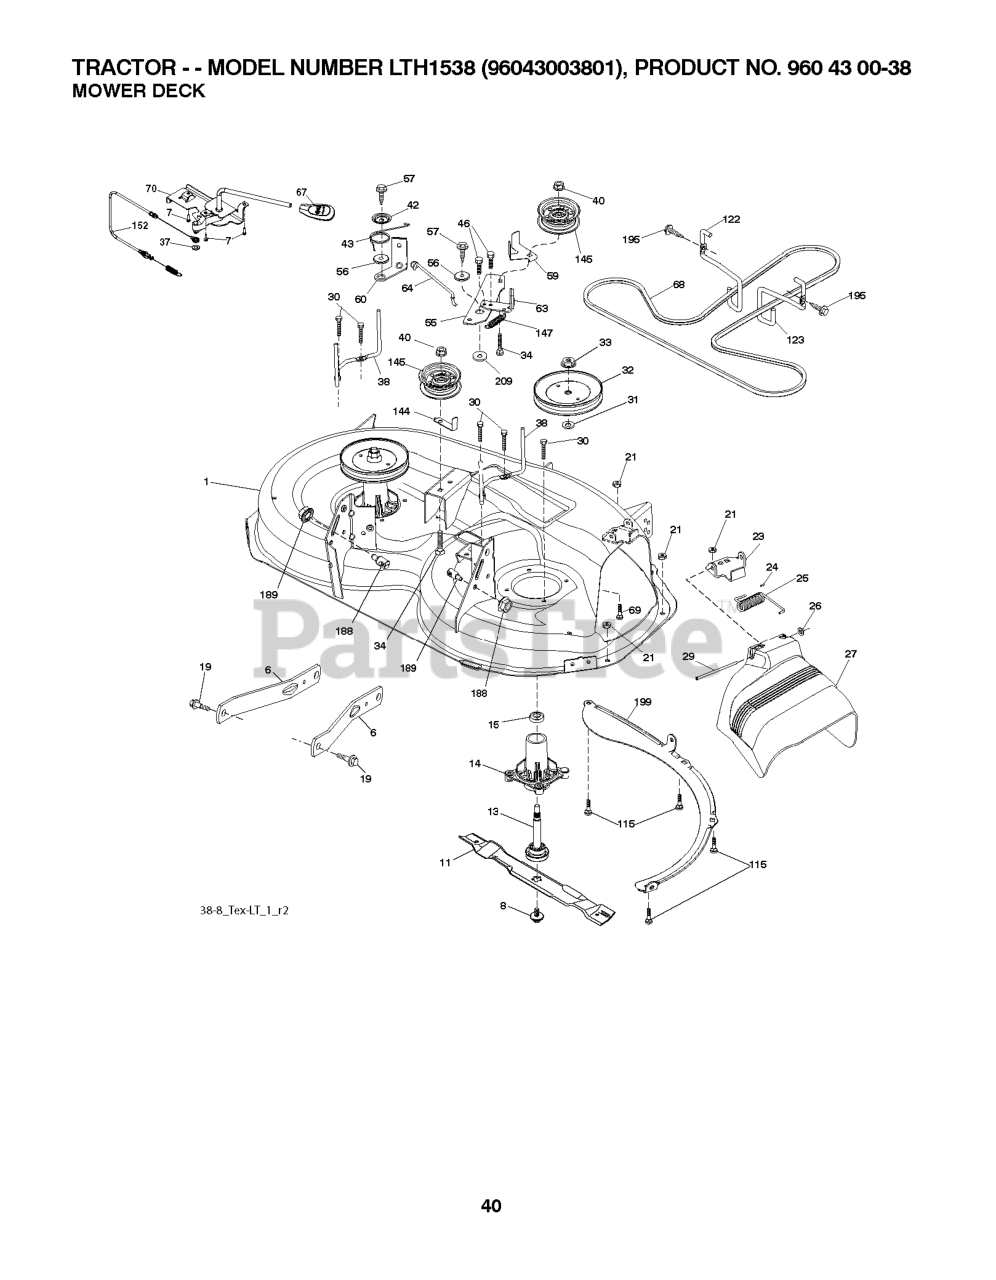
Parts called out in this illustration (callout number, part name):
1	MOWER HOUSING
6	ARM.SUSPENSION.MOWER.R
7	SCREW.#10 X 0.750.BOS
8	BOLT.WASHER.ASM.7/16-2
11	BLADE 38" PREMIUM
13	SHAFT.ASM.MDRL.N/GREASE.38
14	RP.HOUSING.MANDREL.4PT.
19	BOLT.SHOULDER
21	LOCKNUT
23	BRKT.DEFLECTOR.38"2005+
24	CAP-SLEEVE LT
25	SPRING.TORSION.DEFLECT
26	NUT PUSH M
27	SHIELD, DEFLECTOR
29	ROD.HINGE
30	SCREW, WASHER HEAD
31	WASHER.SPACER.MANDREL
32	PULLEY MANDREL 5.0"
33	NUT.FLANGE.LOCK.TOP
34	BOLT.3/8-16X1.50
37	WASHER
38	KEEPER BELT LH MANDREL
40	NUT LOCK FLG 3/8-16 UNC
42	SPRING.TORSION.BRAKE
43	SRPING.TORSION.RETAINE
46	SCREW.1/4-20X5/8
56	SPACER.RETAINER
57	SCREW 3/8-16X1
59	GUARD, BELT
60	BRAKE.ARM.LH.38"TEX.COATED
63	BRAKE.ASM.RH.38".TEX.COATED
64	LINKAGE.BRAKE.ASM.ZINC
67	HANDLE.CLUTCH.CABLE.LT
69	BOLT
70	CLUTCH.ASM.MANUAL.LT.PRED
115	BOLT.CARR.5/16-18X5/8.SHORT
116	BOLT M
117	WHEEL.GAGE.HALF.SPOKED
118	LOCKNUT
119	WASHER.5/16.FLAT.STE.STD.
122	KEEPER BELT ENGINE LH
123	KEEPER BELT RH
144	KEEPER.BELT.IDLER.PLATED
145	PULLEY.IDLER.FLAT
147	SPRING RETURN
149	SPRING.RETAINER.YELLOW.ZINC
152	CLUTCH CABLE
188	STUD.FASTNER.W/ANTI-ROTATE
189	NUT LOCK HEX FLANGE 5/16-18
195	SCREW, 3/8-16X3/4
199	BAFFLE.VORTEX.FRONT.38"
209	WASHER 12/32X2X10GA
